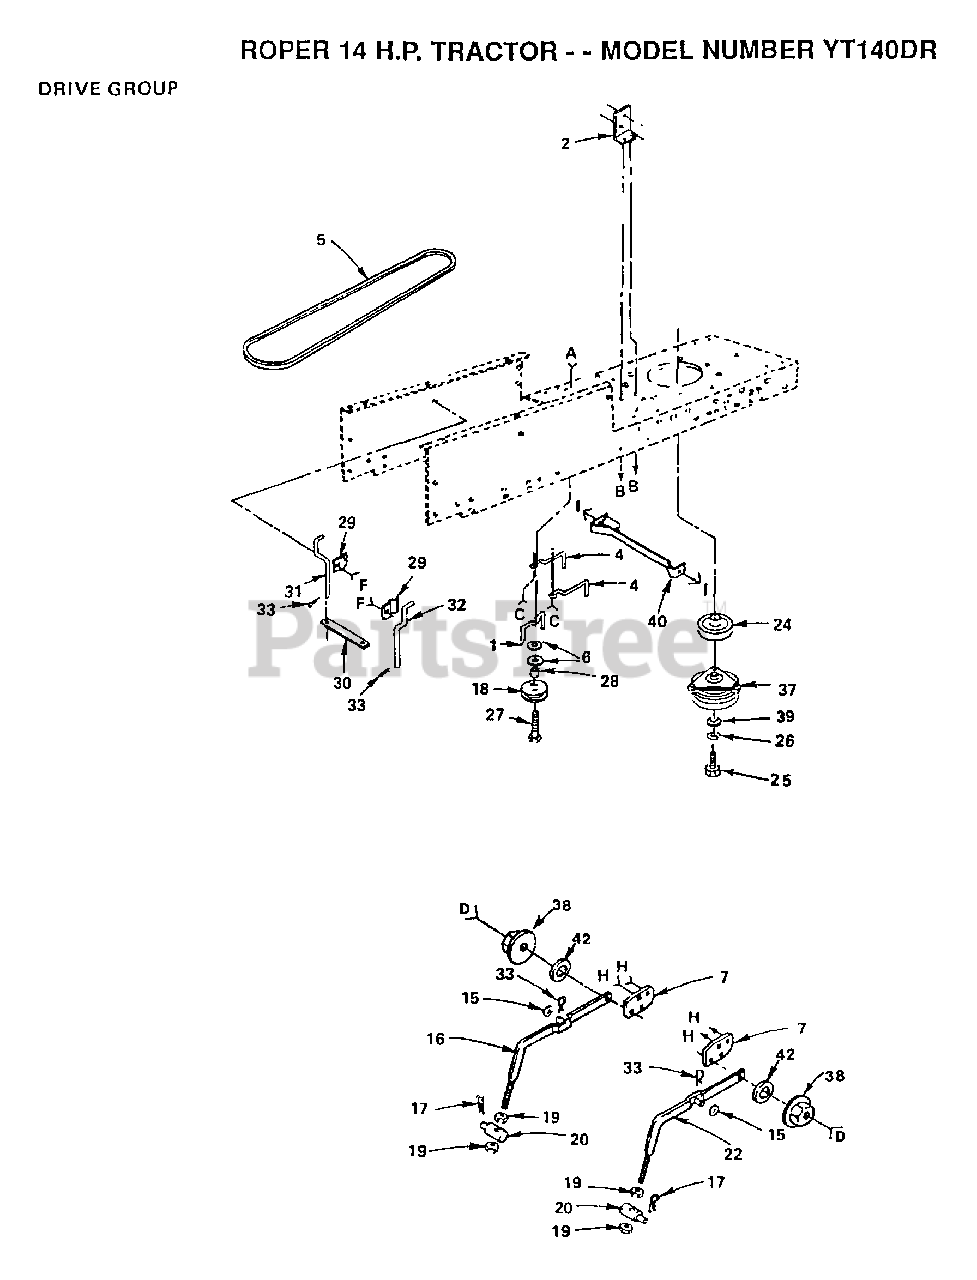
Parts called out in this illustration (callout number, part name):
1	BELT KEEPER LT
2	BRACKET LT
4	"KEEPER,BLT ENG LT"
6	WASHER
7	"BRACKET, SUSPE T"
16	LH SUSP ARM ASM
17	SPRING H
19	NUT
22	RH SUSP ARM ASM
26	LOCKWASHER
27	BOLT
28	SPACER T
29	CLAMP LT
33	SPRING.RETAINER
38	NUT SPECIAL T
39	WASHER T
42	WASHER T
